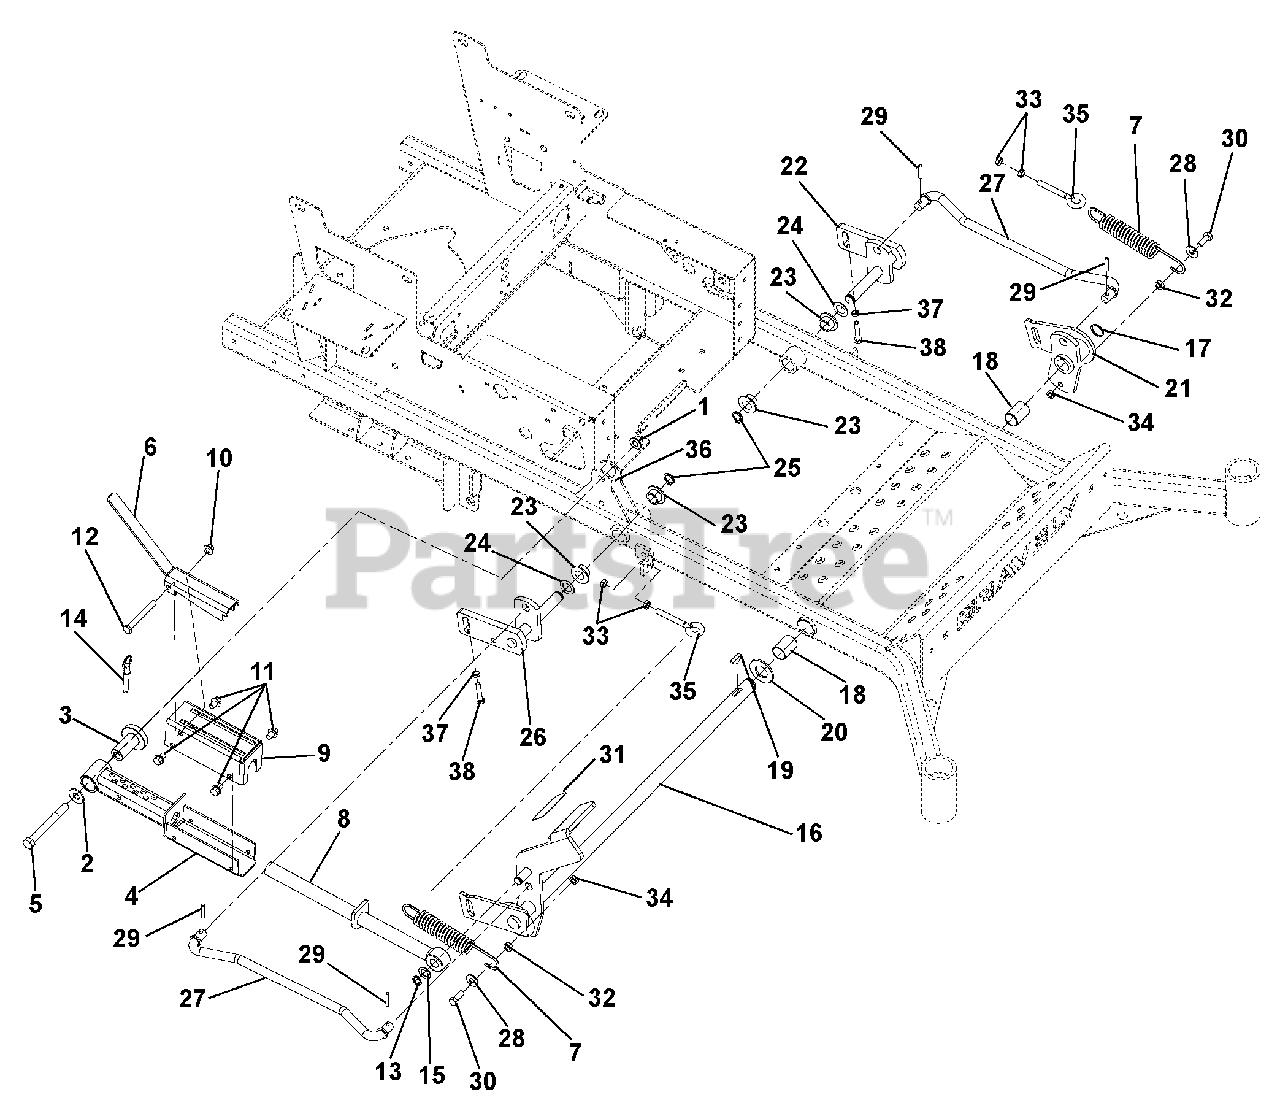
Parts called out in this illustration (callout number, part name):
1	Nut, Locking Top Flange .50-13
2	Washer, Flat Steel .531 x 1.25 x .10
3	Bearing, Pedestal
4	Weldment, Mechanical Lift Cover
5	Bolt, Hex .50-13 x 4.50 Grade 5
6	Mechanical Deck Lift Lock Lever
7	Spring, Tension .162 x 1.25 x 8.25 Weldment 25
8	Weldment, Mechanical Lift Shaft
9	Weldment, Mechanical Lift Cover
10	Nut, Nyloc Flange 3/8-16
11	Screw, Tapping .38-16 x .50 Hex Washer Head
12	Bolt, Hex .38-16 x 3.25 Grade 5
13	Ring, Retaining External .625 x .050
14	Pin, Spring Ball .375 O.D. x 1.50
15	Washer, Flat Steel .630 x 1.005 x .062
16	Weldment, 100I Foot Operated Deck Lift
17	Ring, Retaining External 1.00 x .078
18	Bushing 1.00 ID x 1.125 OD x 1.50
19	Key, Woodruff .25 x 1.00
20	Washer, Flat Steel 1.062 x 2.0 x .134
21	Weldment, Left Hand Mower Lift Arm
22	Weldment, Left Hand Rear Lift Arm
23	Bushing, Flange Nylon .762 x 1.0 x .580 x 1.48
24	Washer, Hardened Steel .758 x 1.23 x .031
25	Ring, Retaining External .689 x .077
26	Weldment, Right Hand Rear Lift Arm
27	Rod, Lift Assist
28	Washer, Flat Steel .438 x 1.00 x .083
29	Pin, Roll .25 x 1.25 Stainless Steel
30	Bolt, Hex .38-16 x 1.00 Grade 5
31	Grip, Pedal
32	Bushing, Sleeve .377 x .624 x .235
33	Nut, Hex-Jam .375-16
34	Nut, Locking-Jam-Center .375-16
35	Bolt, Eye .375-16 x 2.50
36	Spacer, .516 ID x 1.000 OD x .875
37	Nut, Jam .312-18
38	Bolt, Hex .312-18 x 1.50 FTH Grade 5
